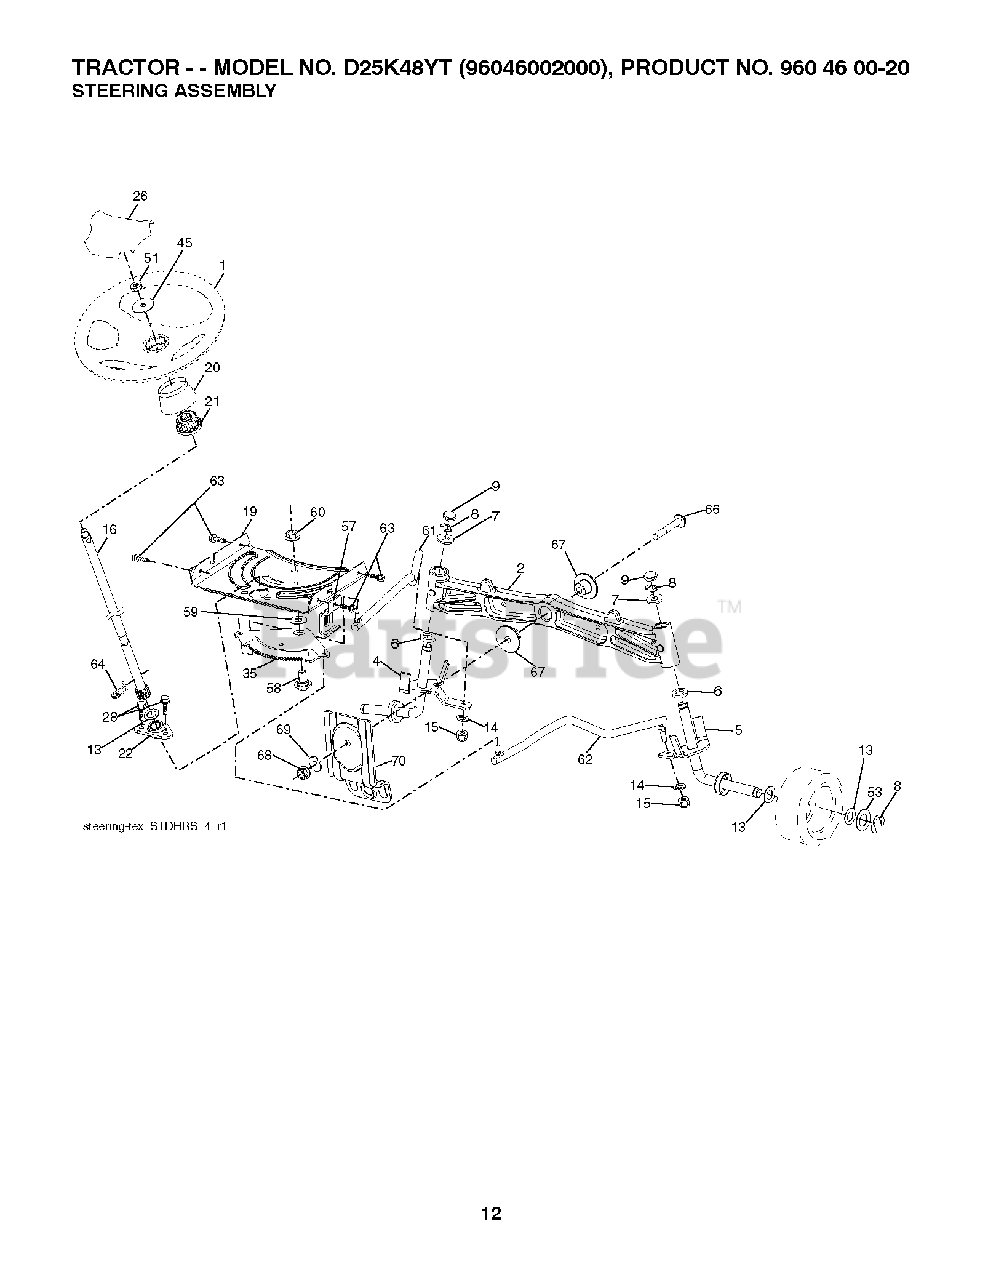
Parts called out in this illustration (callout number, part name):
1	WHEEL.STEERING.STDSRR.BLK/OV
2	AXLE.CAST.IRON
4	SPINDLE.WELDED.LH.15"TEX
5	SPINDLE.WELDED.RH.15"T
8	RING CLIP
9	CAP.SPINDLE.BLACK
14	WASHER, LOCK 3/8
15	NUT CROWNLOCK 3/8-24
16	SHAFT, STEERING
19	PLATE.STEER.DDL.NLT/NG
20	BOOT.STEERING.
21	ADAPTER, WHEEL STNG..
22	STEERING.SUPT.LOWER.
26	INSERT, WHEEL STEERING
28	SCREW, 3/8-16X3/4
35	GEAR.SECTOR.PLATE.DDL.
45	WASHER.11/32
51	NUT.HEX.1/2-20
53	WASHER.HARDENED
57	BRKT.UPSTOP.GT/LT.TEX
58	BOLT.SHOULDER.SECTOR.P
59	WASHER.THURST.SECTOR.S
60	NUT FLANGE LOCK 5/8-11
61	DRAGLINK.LH.BALLSTUD.D
62	DRAGLINK.RH.BALLSTUD.D
63	SCREW
64	RETAINER.CLIP.SPRING.S
66	BOLT HEX FGHD 7/16-14 X 3 SERR
67	BUSHING.PM.FRONT AXLE
68	NUT.LOCK.FLANGE.7/16
69	WASHER.1.5X.505X.118
70	BRKT.DECK.SUSPENSION.F
